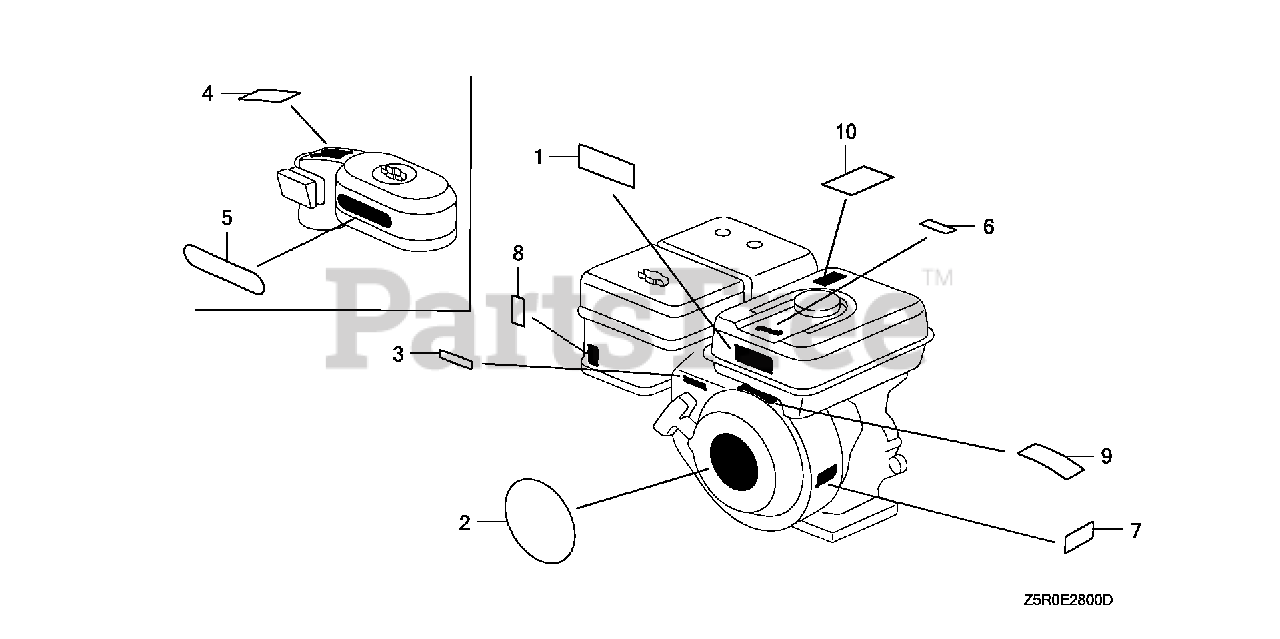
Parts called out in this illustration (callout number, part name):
1	MARK, OPERATOR CAUTION (PICTOGRAPH)(MADE IN JAPAN)
2	EMBLEM (GX390) (HONDA)
3	MARK, THROTTLE INDICATION
